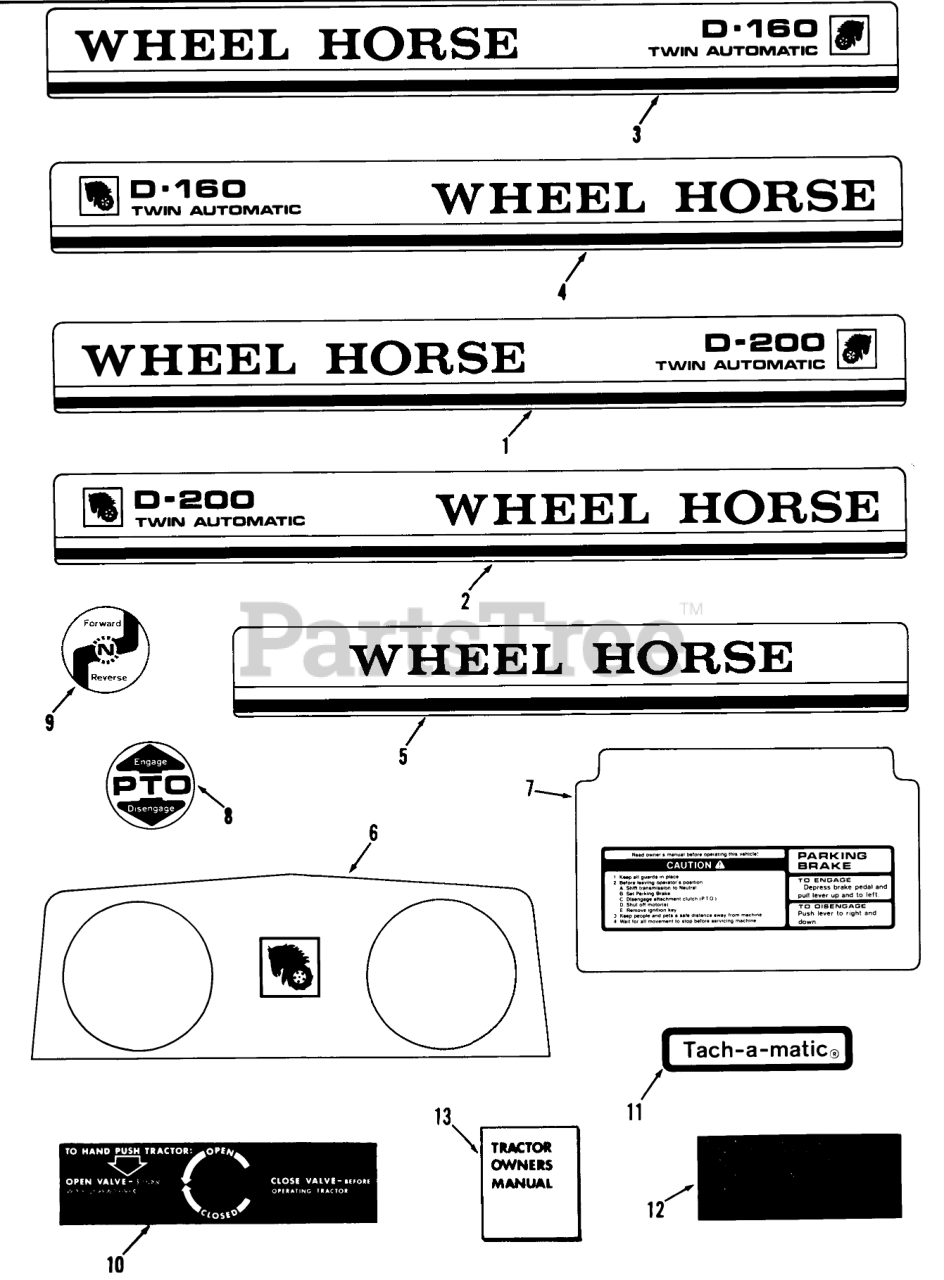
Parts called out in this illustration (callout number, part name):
1	Decal-D-200 Twin Automatic RH
2	Decal-D-200 Twin Automatic LH
3	Decal-D-160 Twin Automatic RH
4	Decal-D-160 Twin Automatic LH
5	Decal-Rear
6	Decal-Headlight Plate
7	Decal-Caution & Parking Brake
8	Decal-Clutch Lever
9	Decal-Motion Control Lever
10	PUSH VALVE DECAL
11	DECAL-TACHAMATIC
12	Decal-Maintenance
13	Owner-s Manual
